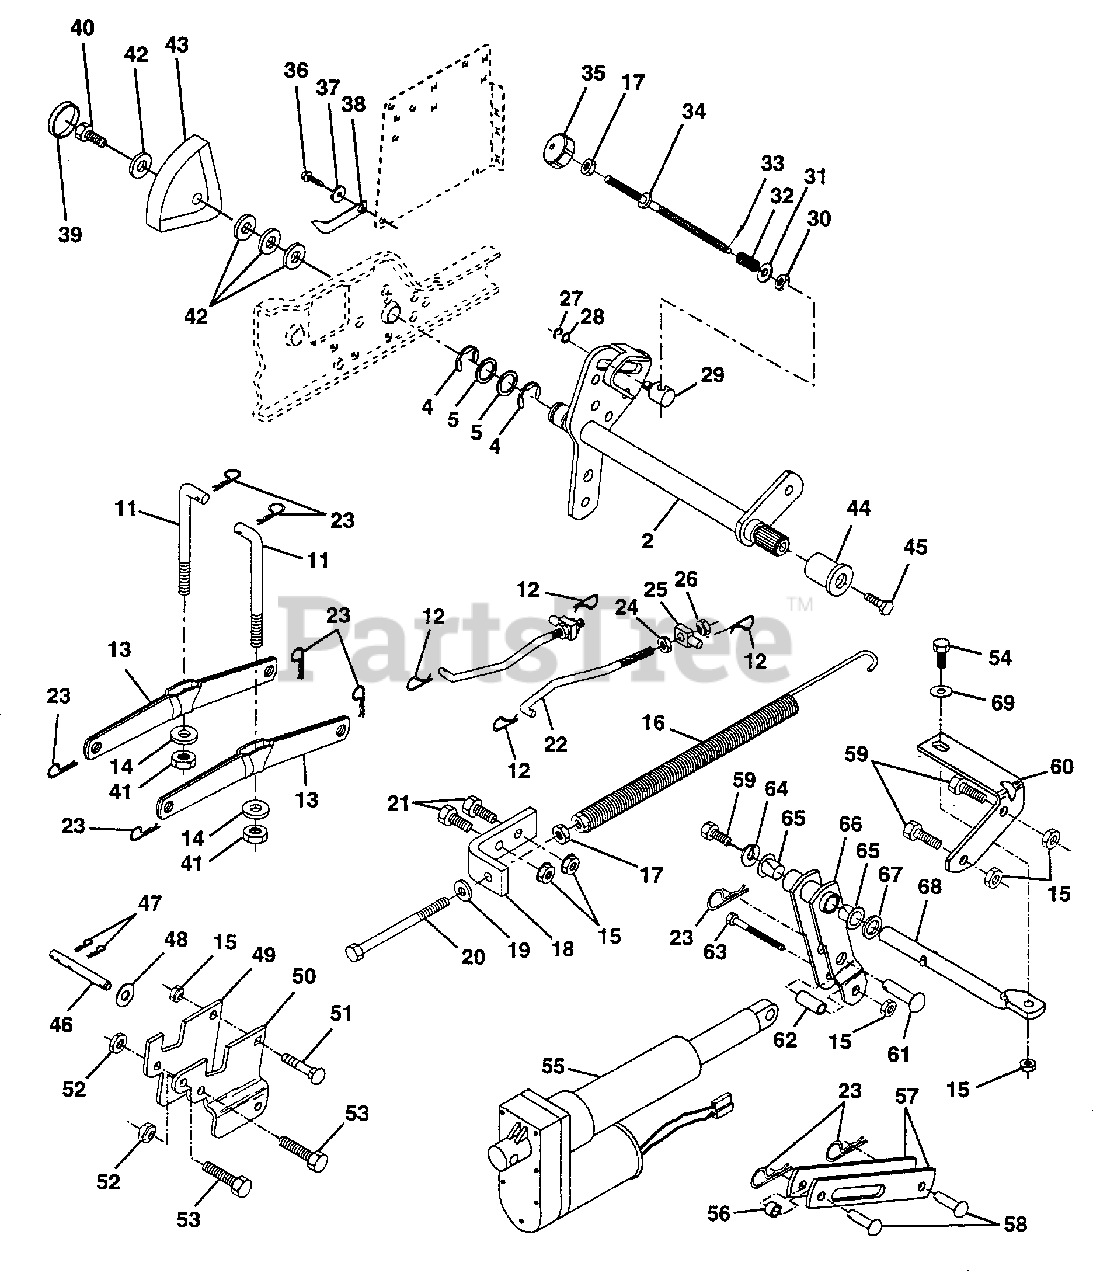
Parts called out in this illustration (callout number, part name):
2	SHAFT.LIFT.VGT.95
4	E-RING
5	WASHER
11	LINK.LIFT.MWR.VGT
12	RETAINER.SPRING
13	ARM SUSP REAR
14	BEARING PVT LH
17	NUT
18	BRACKET SPRING AS
19	WASHER
20	BOLT-ADJ SPRING T
21	BOLT
22	LINK.FRONT
24	NUT
25	TRUNION
26	NUT.LK.W/WSH.1/2.
27	KLIP RING
28	WASHER
29	TRUNION LT
30	NUT T
31	WASHER
32	SPRING.COMP.INF.H
34	ROD.ADJ.LIFT
35	KNOB INF 3/8-16
36	SCREW
37	WASHER T
38	POINTER HGT IND
39	"PLUG,HOLE"
41	NUT.CROWNLOCK.3/8
42	WASHER
43	HEIGHT INDICATOR
44	LIFT HUB-LEVE T
45	BOLT
46	PIN.ACTUATOR
48	WASHER
49	BRACKET.ACTUAT.LH
50	BRACKET.ACTUAT.RH
51	BOLT.3/8-14X1.25
52	NUT.7/16
53	BOLT.HX.HD.7/16
55	ACTUATOR.07823175
56	SPACER.500X384X23
57	LINK.LIFT.ELECT.
58	PIN.PIVOT
60	BRACKET.ROD.PIVOT
61	PIN.PIVOT
62	TUBE GT
63	BOLT-HEX EAK
64	LOCKWASHER
65	NYLINER.ROD.PIVOT
66	ARM.ASM.PIVOT
67	WASHER
68	ROD.SUPPORT.PIVOT
69	WASHER
